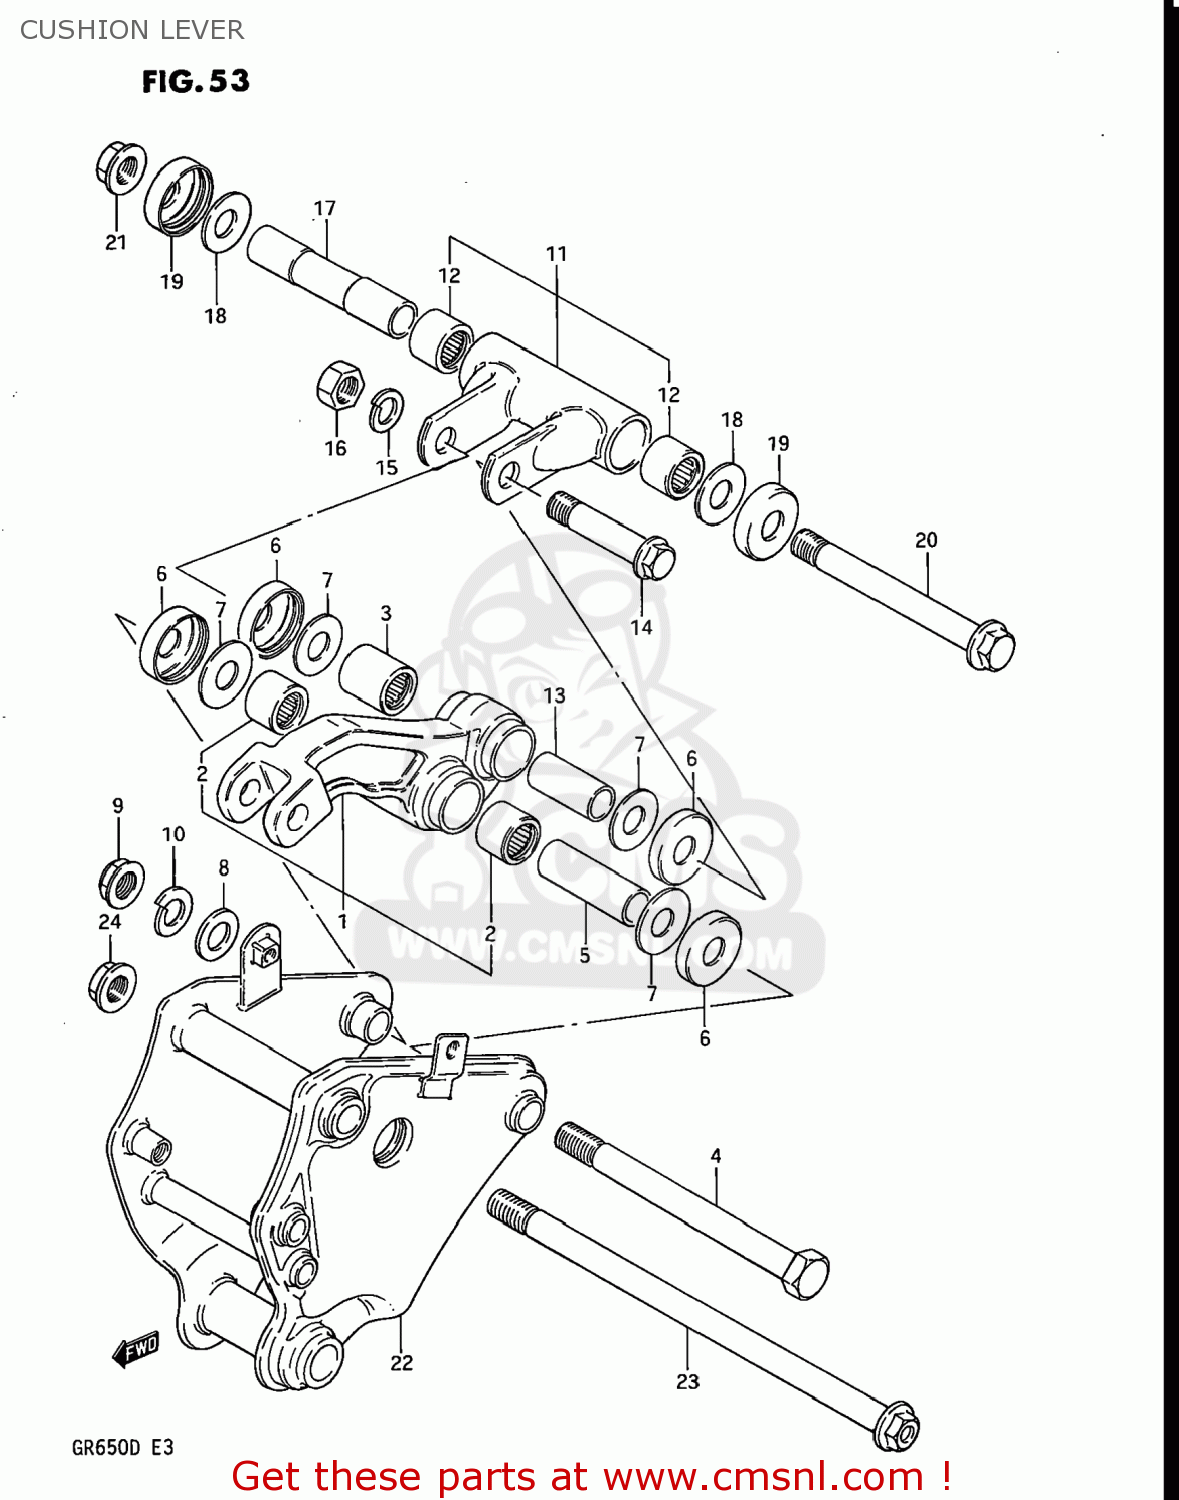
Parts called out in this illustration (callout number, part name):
1	LEVER SET,REAR CUSHION
2	ROLLER BEARING (17X24X2
3	ROLLER BEARING (17X24X25)
4	SHAFT,REAR CUSHION LEVER
5	SPACER,REAR CUSHION LEVER
6	COVER,RR SWGARM DUST SEAL
7	WASHER
8	WASHER
9	NUT 12MM
10	WASHER,LOCK 12
11	LEVER SET,REAR CUSHION
12	ROLLER BEARING (17X24X2
13	SPACER,RR CUSHION LEVER ROD UP
14	BOLT, UPPER
15	WASHER,LOCK 12
16	NUT
17	SPACER,RR CUSHION LVR ROD LOW
18	WASHER
19	COVER,RR SWGARM DUST SEAL
20	BOLT
21	NUT
22	BRACKET,REAR SHOCK ABSORBER
23	BOLT, BRACKET
24	NUT
